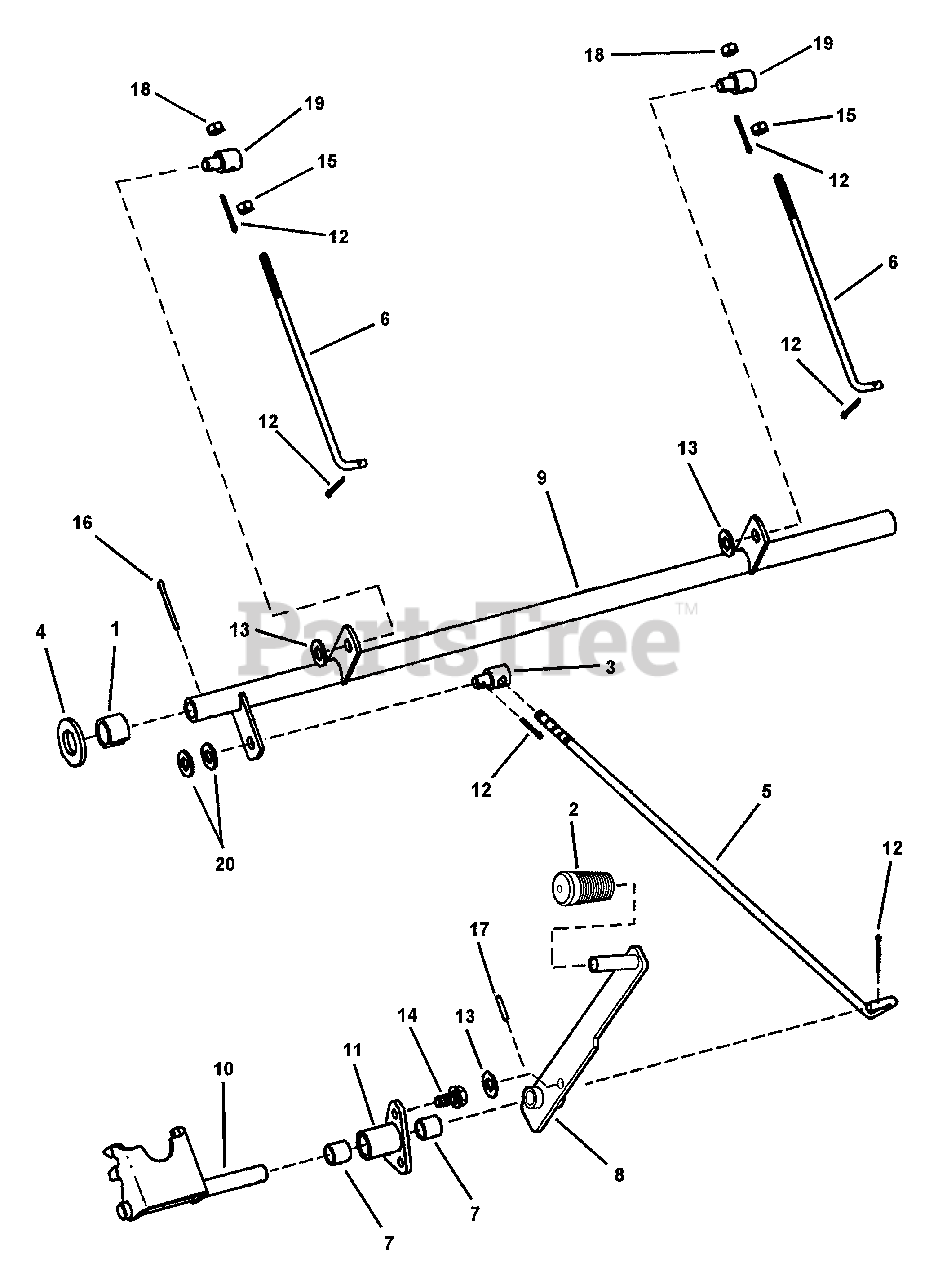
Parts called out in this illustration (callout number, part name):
1	RING, Rear Lift Arm
2	GRIP, Park Brake Lever
3	SWIVEL, Adjustable (3/8-24 thread)
4	WASHER, 3/4 I.D. x 1-1/2 O.D. x 9/64" Flat
5	ARM, Brake Lift (3/8-24 thread)
6	ROD, Hydrostatic Brake (1/4-28 thread)
7	SLEEVE Bearing, 1/2 I.D. x .629
8	WELDMENT, Parking Brake Arm
9	WELDMENT, Brake Shaft
10	WELDMENT, Joystick Lockout Bracket
11	WELDMENT, Support Plate
12	COTTER-PIN, 3/32 x 3/4"
13	WASHER, 3/8" Flat
14	SCREW, 5/16-18 x 5/8" Hex Washer Face Self-Tap
15	HN, 1/4F GR5 YZ
16	COTTER PIN, 1/8 x 1-1/4"
17	PIN, Roll 1/8 x 3/4"
18	NUT, 1/4-28 Hex Nyloc
19	SWIVEL, 1/4" Smooth
20	WASHER, 5/16" Flat
